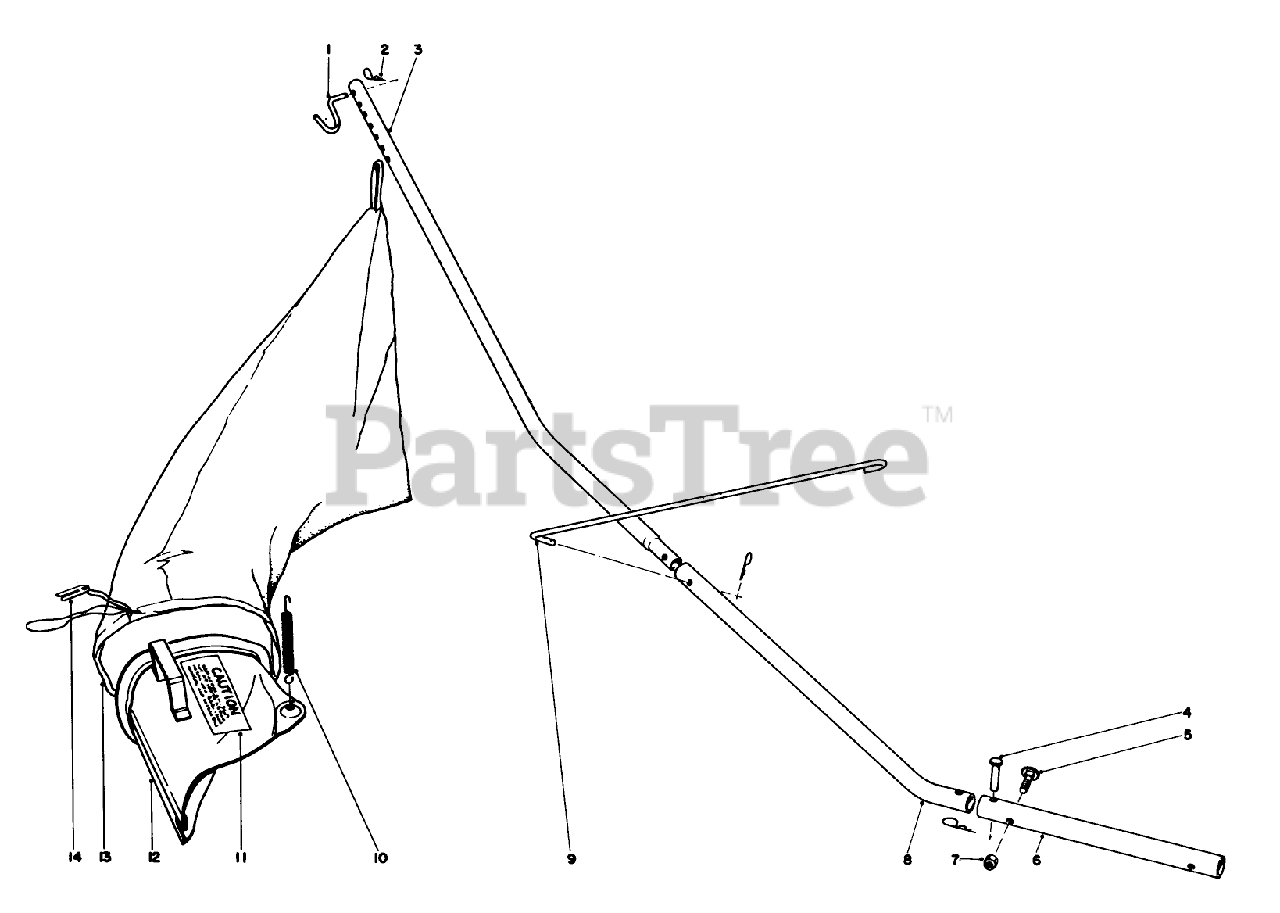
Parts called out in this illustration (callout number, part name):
2	PIN-COTTER
3	Long Bag Arm
5	HANDLE SCREW
6	Frame Bag Rod
7	NUT-LOCK, CONE
8	Bag Rod Extension
9	Bag Rod Support
10	Spring
11	Decal
12	Bag Chute Assembly (Incl. Ref. No-s. 10, 11 & 12)
13	Bag Assembly (Incl. Ref. No. 14)
14	BAG CORD FASTENER
